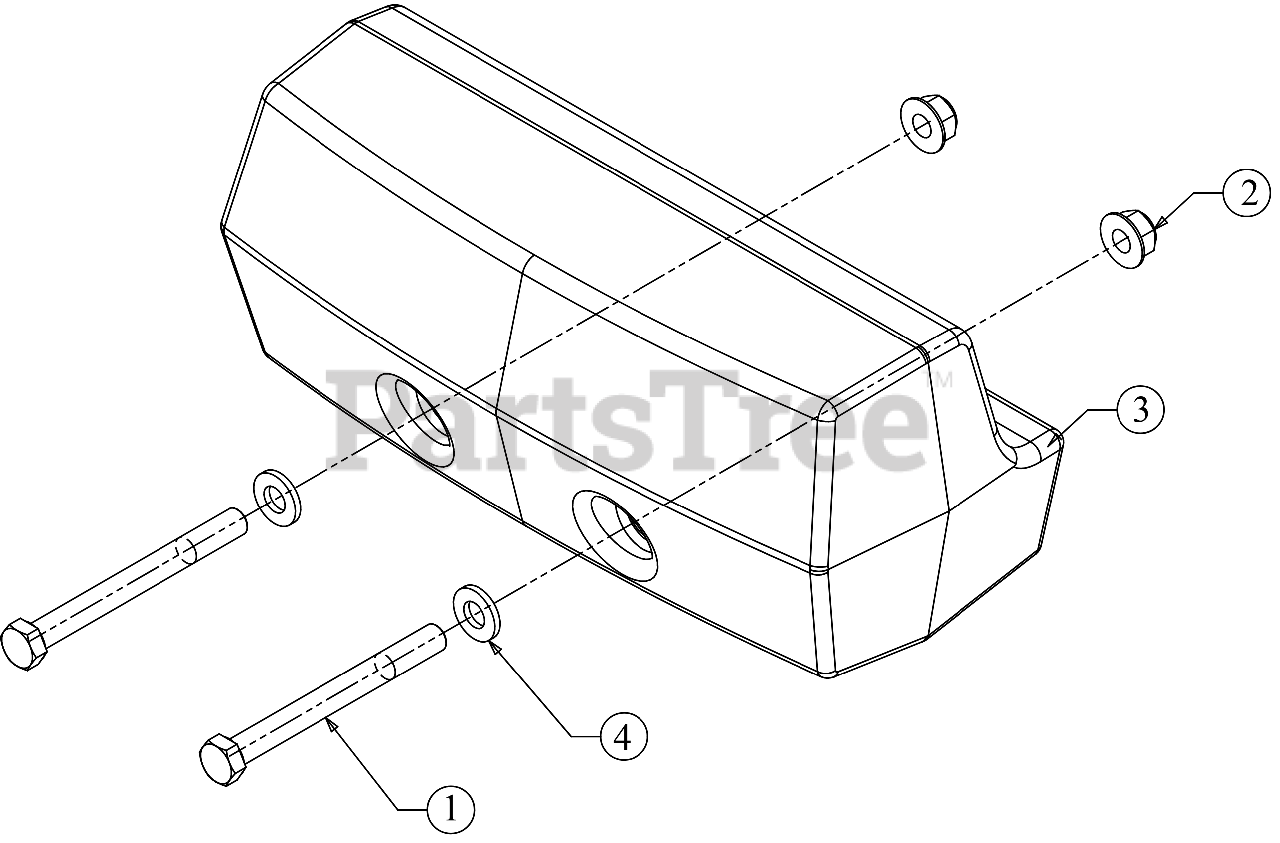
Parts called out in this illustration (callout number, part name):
1	BOLT-HEX 1/2-13X5.0
2	NUT-FLGLK 1/2-13 NYLON
3	COUNTERWEIGHT
4	WASHER-FL
